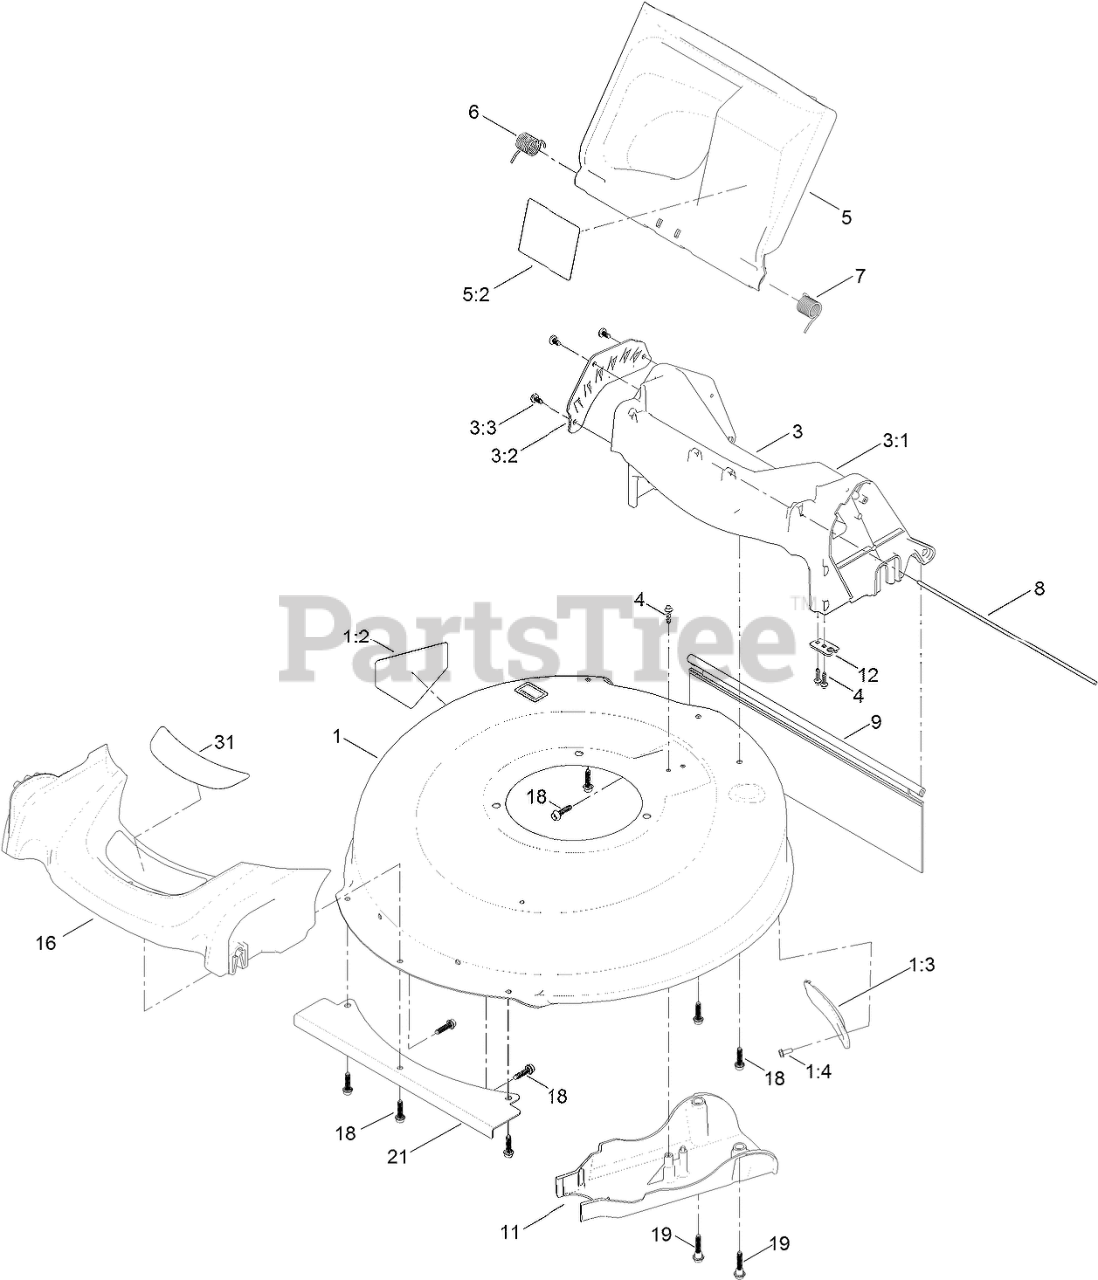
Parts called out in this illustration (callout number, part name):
1	HOUSING ASM
1:2	DECAL-DANGER
1:3	COVER-BELT
1:4	SCREW-TAPTITE
3	CHUTE ASM
3:1	CHUTE
3:2	PLATE-HOC
3:3	SCREW-PLASTIC TPH
4	SCREW-HWH
5	REAR DEFLECTOR ASM
5:2	DECAL-WARNING
6	SPRING-TORSION
7	SPRING-TORSION
8	ROD-DOOR
9	SHIELD-TRAILING
11	COVER-BELT
12	BRACKET-CABLE
16	BUMPER
18	SCREW-FLANGE, PLASTIC
19	SCREW-SHOULDER, HHF
21	SHIELD-FRONT
31	DECAL-DECK
